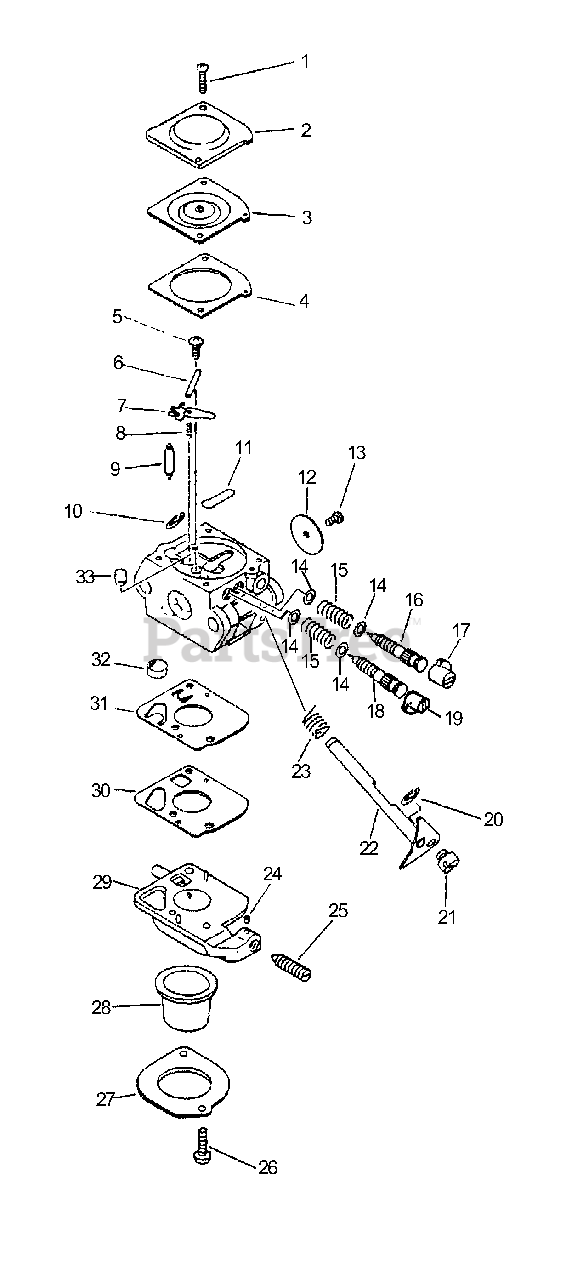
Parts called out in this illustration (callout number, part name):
2	COVER, METERING
3	DIAPHRAGM, METERING
4	GASKET, METERING
5	SCREW, METERING LEVER PIN
6	PIN, METERING LEVER
7	LEVER, METERING
8	SPRING, METERING LEVER
9	VALVE, NEEDLE
10	RING, RETAINING
11	PLUG, WELCH
12	VALVE, THROTTLE
16	NEEDLE - LOW SPEED
17	CAP, LIMITER
18	NEEDLE - HIGH SPEED
19	CAP, LIMITER
20	RING, RETAINING
22	SHAFT, THROTTLE
23	SPRING, RETURN
24	PIECE, FRICTION
25	SCREW, IDLE ADJUST
26	SCREW, RETAINER
27	RETAINER, PURGE BULB
28	BULB, PURGE
29	BASE, PURGE
30	GASKET, PUMP
31	DIAPHRAGM, PUMP
32	STRAINER
33	NOZZLE, CHECK VALVE
